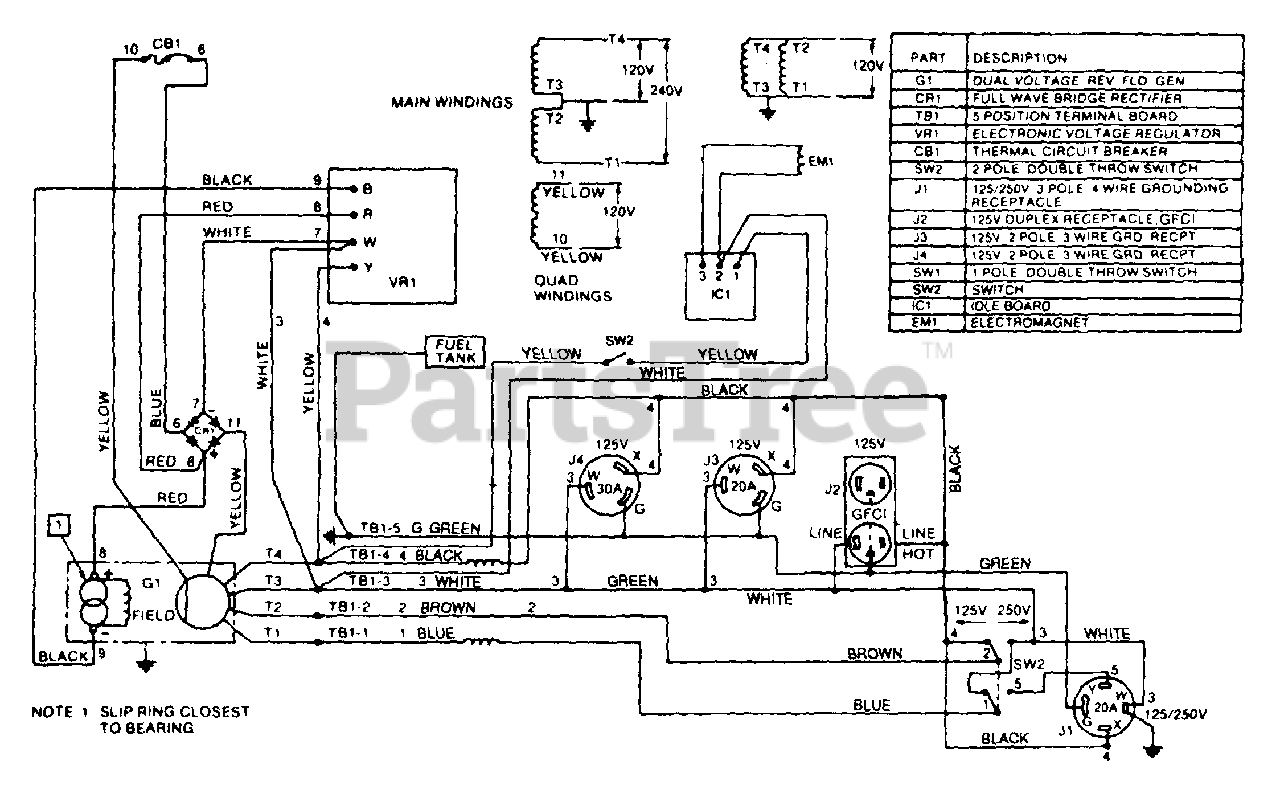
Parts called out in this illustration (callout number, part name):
1	END BELL
2	NUT-Hex (1/4-20)
3	WASHER-Lock
4	SCREW-Hex Hd. (3/8-16 X 7/8")
5	STATOR SHELL
6	WASHER-Lock/Int. (1/4")
7	BOLT-Stator
8	SCREW-Machine Pan Hd. (8-32 X 3/8")
10	BRUSH HOLDER
11	SCREW-Thread Rolling (8-32 X 1/2")
12	WASHER-Flat (#8)
13	WASHER-Lock (#8)
14	SCREW-Hex Tap (8-32 X 3/4")
15	RECTIFIER
16	BRUSH HEAD
17	BEARING
19	WASHER-Flat (5/16)
20	WASHER-Lock (5/16)
21	BOLT-Rotor
22	BRUSH HEAD COVER
23	GROMMET
25	NUT-Hex (8-32)
26	WASHER-Lock (#8)
27	BLOCK-Terminal
28	PANEL-Cover
29	CABLE TIE
30	SWITCH (DPDT)
31	SCREW-Pan Hd. (#8-32 X 1/2")
32	VOLTAGE REGULATOR
33	SCREW-Shoulder
34	RECEPTACLE, GFCI (Nema 5-15R)
35	RECEPTACLE-Locking (Nema L5-20R)
36	RECEPTACLE-Locking (Nema L5-30R)
37	RECEPTACLE-Locking (Nema L14-20R)
38	CIRCUIT BREAKER-2.5 Amp
39	SCREW-Hex Hd. (5/16-18 X 1)
40	NUT-Wing (5/16-18)
41	WASHER-Lock (5/16)
42	NUT-Hex (5/16-18)
43	CLAMP-Cable
44	SCREW-Pan Hd. (8/32 X 5/8")
45	SWITCH-Rocker
46	SCREW-Machine Pan (8-32 X 3/8")
47	CONTROL PANEL
48	DECAL-Schematic
49	IDLE CONTROL
50	NUT-Speed
51	DECAL-Warning
